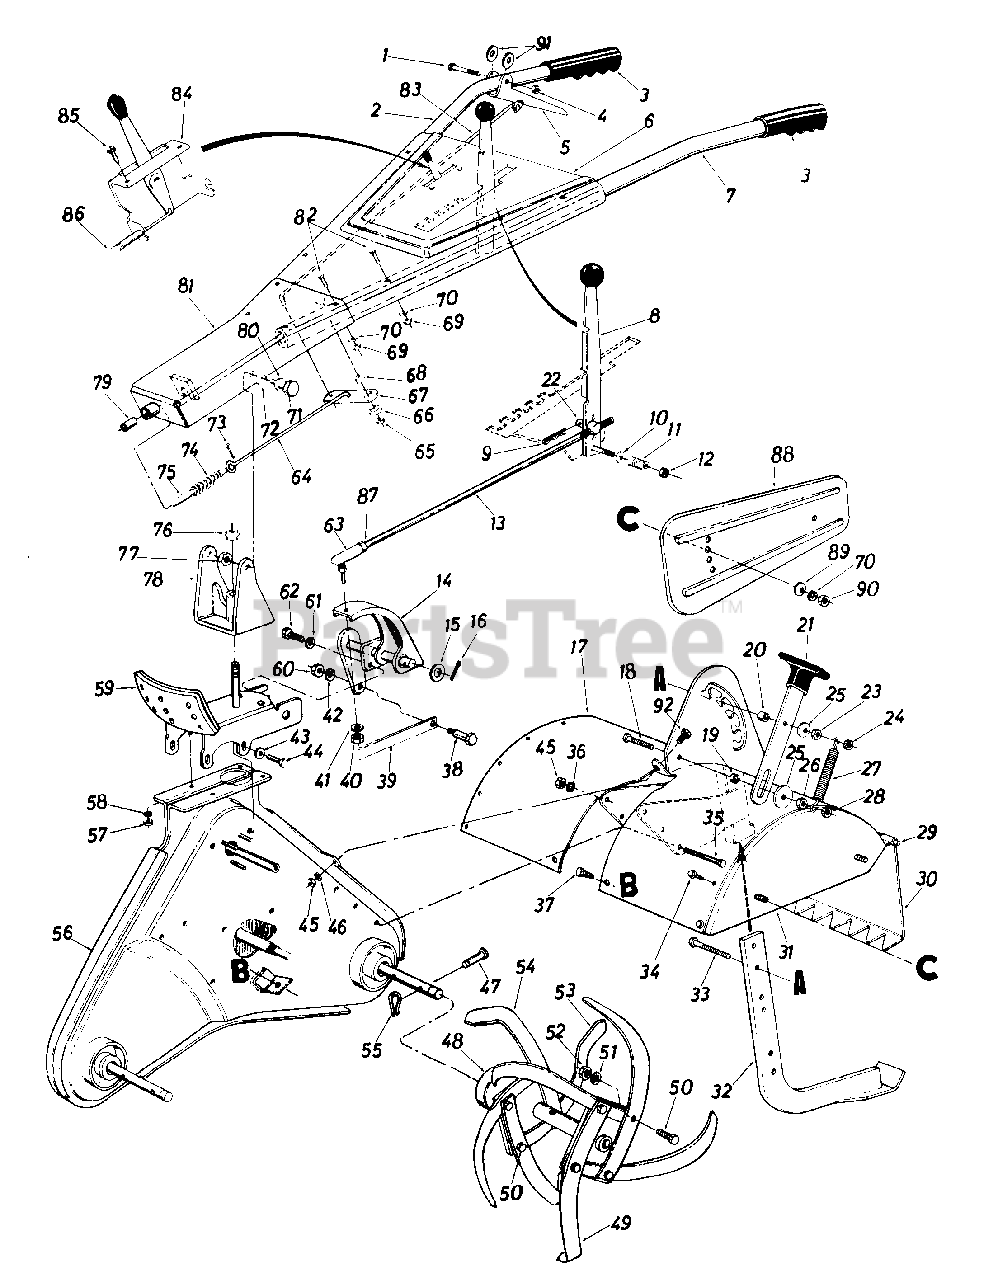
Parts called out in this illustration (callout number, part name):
1	Hex Bolt 1/4-20 x 1.75" Lg.
2	Handle - R.H.
3	Grip
4	Hex Cent. L-Nut 1/4-20 Thd.
5	Clutch Grip
6	Handle Panel Ass'y.
7	Handle - L.H.
8	Clutch Handle Ass'y.
9	Hairpin Cotter
10	Belleville Wash. .38" I.D.
11	Compression Spring .88" O.D. x .81" Lg.
12	Hex Cent. L-Nut 3/8-24 Thd.
13	Gear Shift Rod
14	Pivot Horn Ass'y.
15	Fl-Wash. .630 I.D. x 1.0" O.D. x .063
16	Cotter Pin 1/8" Dia. x .75" Lg.
17	Tine Shield Ass'y.
18	Hex Bolt 3/8-16 x 1.5" Lg.
19	Spacer .38 I.D. x .50 O.D. x .18 Lg.
20	Spacer .38 I.D. x .50 O.D. x .38 Lg.
21	Depth Bar Handle Ass'y. w/Knob
22	Ferrule
23	Hex Nut 3/8-16 Thd.
24	Hex Ins. L-Nut 3/8-16 Thd.
25	Fl-Wash. .38 I.D. x 1.50 O.D. x .13
26	Hex Nut 3/8-16 Thd.
27	Spring - Depth Bar
28	Hex Ins. L-Nut 3/8-16 Thd.
29	Hinge Rod
30	Tine Shield Hinge Flap Ass'y.
31	Side Cover Tine Shield - L.H.
32	Depth/Drag Bar Ass'y.
33	Hex Bolt 3/8-16 x 1.75" Lg.
34	Hex Wash. Hd. Self-Tap Scr. 1/4-20 x .50" Lg.
35	Hex Bolt 3/8-24 x 3.0" Lg.
36	L-Wash. 3/8" I.D.
37	Hex Wash. Hd. Self-Tap Scr.
38	Shoulder Bolt .50" Dia. x .25" Lg.
39	Control Bracket
40	Hex Ins. L-Nut 3/8-24 Thd.
41	L-Wash. 3/8" I.D.
42	L-Wash. 3/8" I.D.
43	Belleville Wash.
44	Hex Wash. Hd. Self-Tap Scr.
45	Hex Nut 3/8-24 Thd.
46	L-Wash. 3/8" Scr.
47	Clevis Pin
48	Tine Adapter Ass'y.
49	L.H. Tine Ass'y. Comp.
50	Hex Bolt 3/8-24 x 1.25" Lg.
51	L-Wash. 3/8" I.D.
52	Hex Nut 3/8-24 Thd.
54	Tine - L.H.
55	Hairpin Cotter
56	Chain Case Ass'y. Comp.
57	Hex Nut 5/16-18 Thd.
58	L-Wash. 5/16" I.D.
59	Handle Positioner Ass'y.
60	Hex Ins. L-Nut 3/8-16 Thd.
61	L-Wash. 5/16" I.D.
62	Hex Wash. Hd. Self-Tap Scr.
63	Rod End 3/8-24 Thd.
64	Lower Handle Control Rod
65	Hex Nut 5/16-18 Thd.
66	Pivot Handle Brg.
67	Pivot Handle Link
68	Bushing Wash.
69	Hex Nut 5/16-18 Thd.
70	L-Wash. 5/16" I.D.
71	Shld. Bolt .500" Dia. x .660
72	Belleville Wash. .505" I.D. x 1.00" O.D.
73	Cotter Pin 1/8" Dia. x .75" Lg.
74	Compression Spring
75	Locking Pin
76	Hex Ins. L-Nut 5/8-16 Thd.
77	Hex Top L-Nut 3/8-16 Thd.
78	Pivot Brkt. Ass'y.
79	Sleeve Brg. .50" I.D. x .62" O.D. x 1.12" Lg.
80	Fl-Wash. .50" I.D. x 1.00" O.D. x .090
81	Handle Mtg. Brkt. Ass'y.
82	Carriage Bolt 5/16-18 x 1.75" Lg.
83	Handle Lock Rod
84	Throttle Control Ass'y. Comp.
85	Hex Wash. Hd. Tap Scr. #8 .50" Lg.
86	Conduit and Wire 63.5" Lg.
87	Hex Jam Nut 3/8-24 Thd.
90	Hex Nut 5/16-18 Thd.
91	Fl-Wash. 1/4" I.D.
92	Hex Bolt 3/8-24 x .75" Lg.
